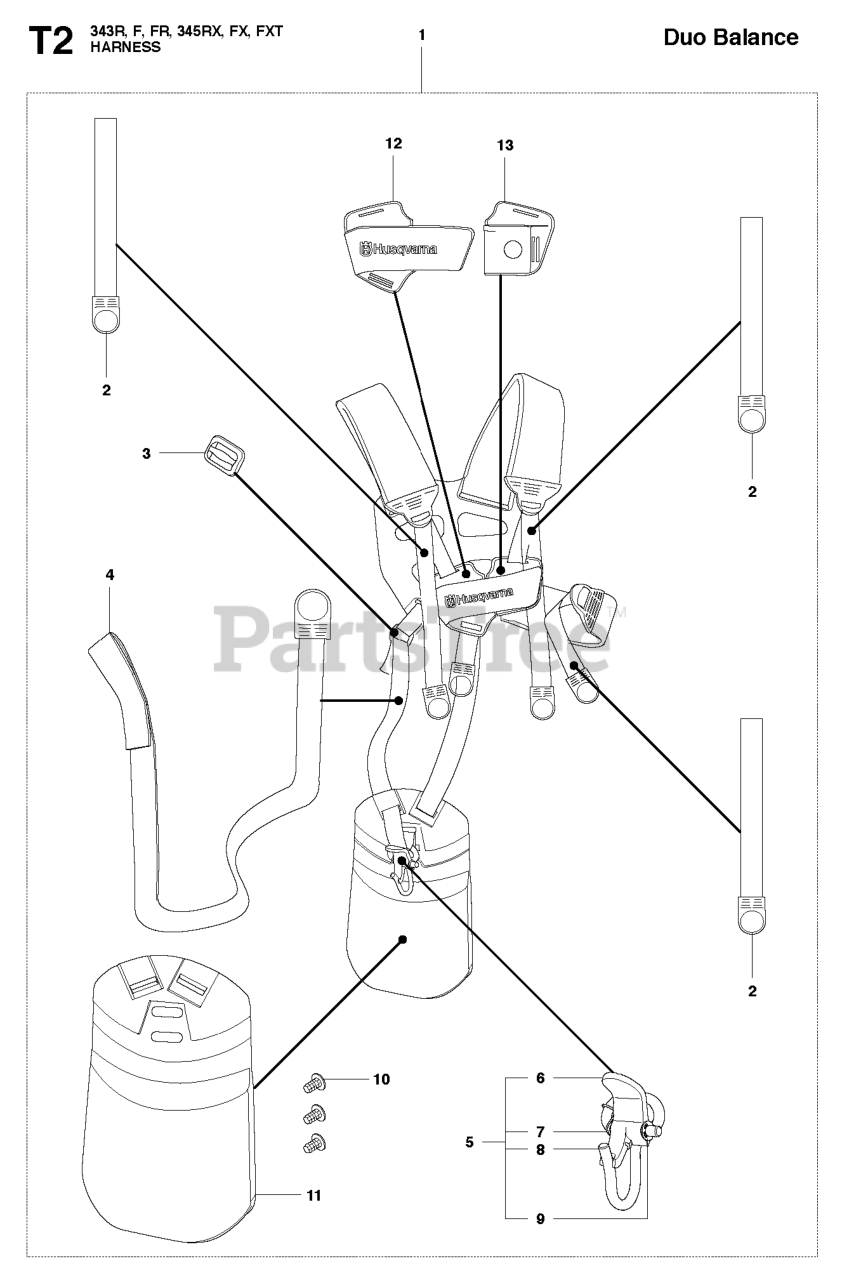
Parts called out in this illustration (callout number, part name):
1	Duo-Bal Harness
1	Harness
3	RP CLIP
5	HARNESS HOOK, COMPLETE
6	CATCH *
7	SPRING
8	HOOK
12	FRONT PIECE
13	FRONT PIECE
